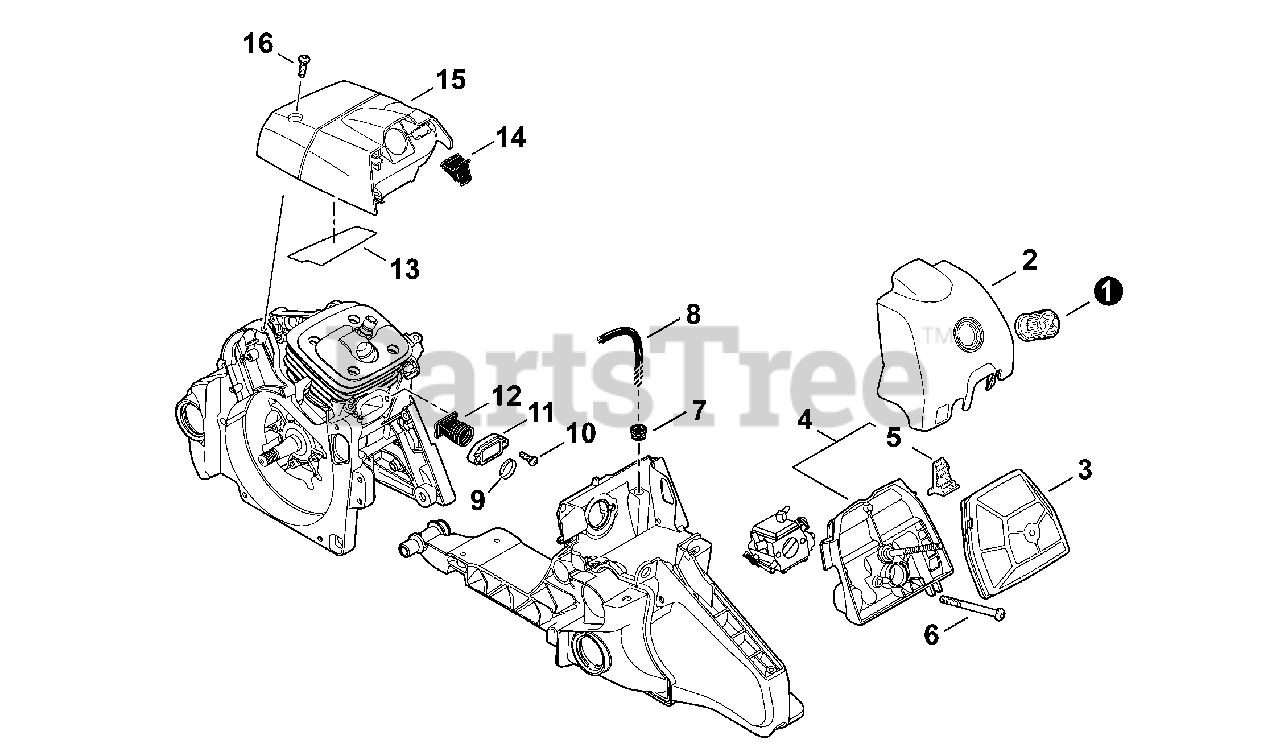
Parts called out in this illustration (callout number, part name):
1	KNOB, AIR FILTER COVER
2	COVER, AIR FILTER
3	FILTER ASSY, AIR
4	CASE, AIR FILTER
5	SHUTTER, AIR
6	BOLT, TORX 5×50
7	GROMMET
8	PIPE, IMPULSE 3×6(8)×160
9	COLLAR 18.6×20.4×4
10	BOLT, TORX 5×16
11	HOLDER, BELLOWS
12	BELLOWS, INTAKE
13	SHIELD, HEAT 75×32×0.15
14	PIPE, INTAKE
15	COVER, ENGINE
16	BOLT, TORX 5×16
